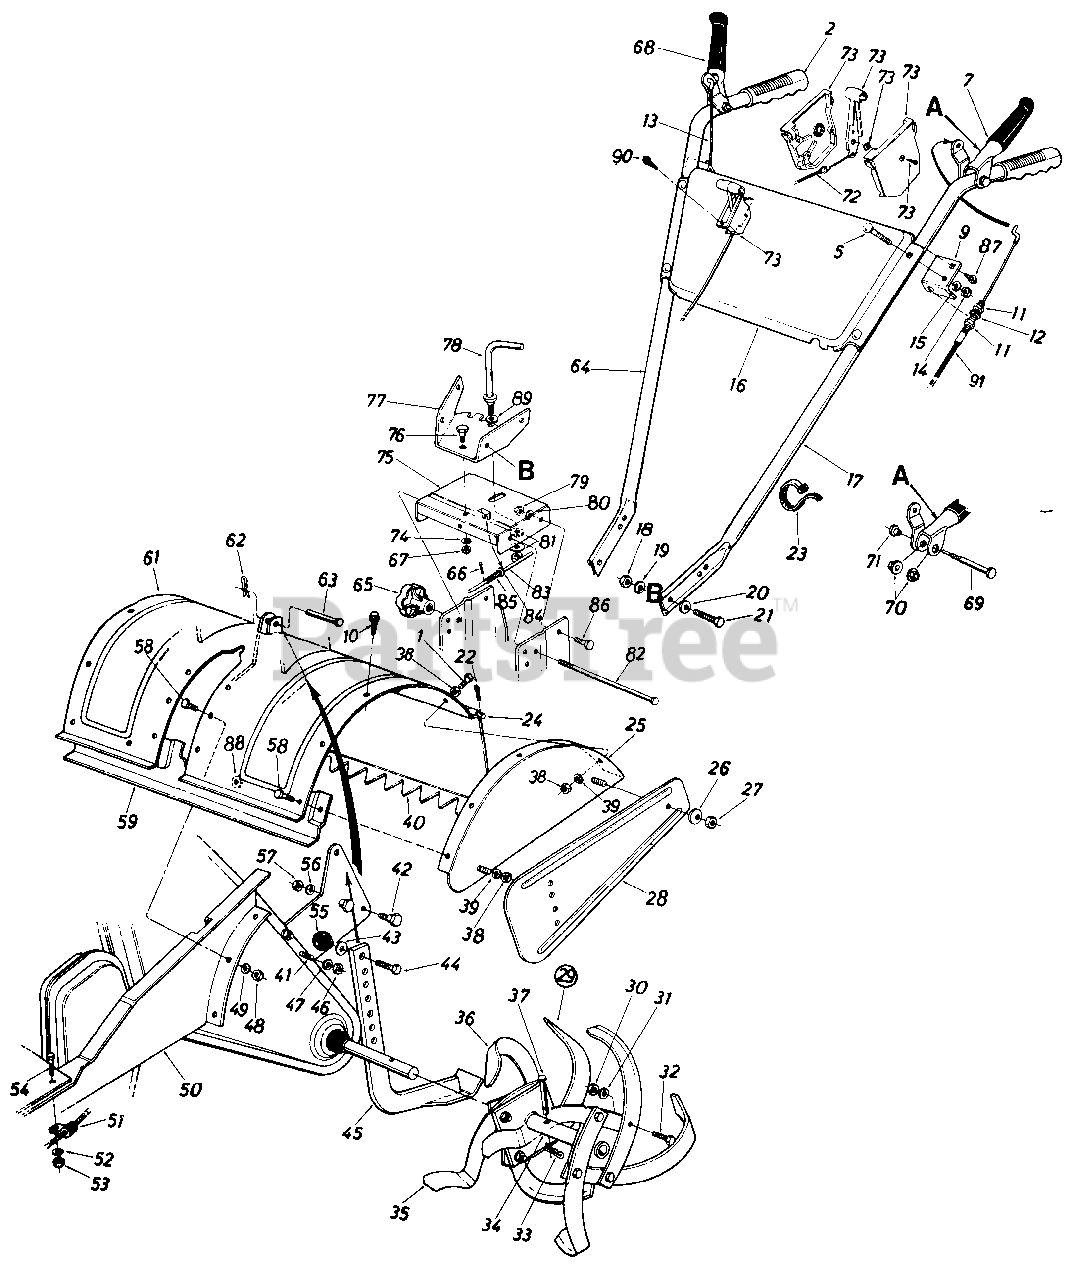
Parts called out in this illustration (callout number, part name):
1	Hex Bolt 5/16-18 x 11/4" Lg.
2	Grip
5	Carr. Bolt 5/16-18 x 1.75"
7	Clutch Grip Ass'y.-L.H.
9	Clutch Cable Bracket
10	Hex Wash. S-Tap Scr. 5/16-18 x .62" Lg.
11	Hex Nut 5/16-24 Thd.
12	L-Wash. 5/16" I.D.
13	Wheel Drive Cable
14	Hex Nut 5/16-18 Thd.
15	L-Wash. 5/16" I.D.*
17	Handle-L.H.
18	Hex Nut 3/8-16 Thd.
19	L-Wash. 3/8" I.D.
20	Bell-Wash. 318" I.D.
21	Hex Bolt 3/8-16 x 1.00" Lg.
22	Cotter Pin 3/32" Dia. x 3/4"*
24	Tiller Flap Rod
27	Hex Nut 5/16-18 Thd.
31	L-Wash. 318" I.D.
32	Hex Bolt 3/8-24 x 1.25" Lg.
33	Hairpin Cotter
38	Hex Nut 5/16-18 Thd.
39	L-Wash. 5/16" I.D.
41	Hex Bolt 5/16-18 x 1.0" Lg.
42	Shld. Bolt 1/2 Dia. x .426"
43	Fl-Wash. 318" I.D. x 518" O.D.
44	Hex Bolt 3/8-16 x 314" Lg.
46	Hex Nut 5/16-18 Thd.
47	L-Wash. 5/16" I.D.
48	Hex Nut 5/16-18 Thd.
49	L-Wash. 5/16" l.D.
52	L-Wash. 5/16" l.D.
53	Hex Nut 5/16-18 Thd.
54	Hex Bolt 5/16-18 x 3/4" Lg.
55	Ball Knob 1-1/4" Dia.
56	L-Wash. 3/8" I.D.
57	Hex Nut 3/8-16 Thd.
58	Hex Bolt 5/16-18 x 75n Lg.
63	Clevis Pin 3/8" Dia.
64	Handle-R . H .
66	Cotter Pin 1/16" Dia. x .75" Lg.
67	Hex Cent. L-Nut 3/8-16 Thd.
68	Clutch Grip Ass'y.-R.H.
69	Shoulder Bolt 38n Dia. x 1.53" Lg.
70	Hex Flange Plastic Bearing
71	Shoulder Nut 1/4-20 Thd.
72	Throttle Control Wire
73	Throttle Control Box Ass'y.
74	Bell-Wash. 40n l.D.
79	Hex Cent. L-Nut 3/8-16 Thd.
80	Bell-Wash. .40" I.D. x .88" O.D.
81	Bell-Wash. 1/2" I.D. x 1.00" O.D.
82	Lock Pin 5/16" Dia. x 8"
83	Lower Sliding Ass'y.
84	Fl-Wash. .291" l.D. x .62n O.D.
85	Compression Spring .36" O.D. x 1.00n Lg.
86	Shoulder Bolt 1/2" Dia. x .170" Lg.
87	Hex Wash. S-Tap Scr. 1/4-20 0 x 60n Lg
88	Bell-Wash. 5/16" I.D.
89	Fl-Wash. 5/8" I.D.
90	Self-Tap Scr. #10 x 1/2" Lg.
91	Tine Control Cable
